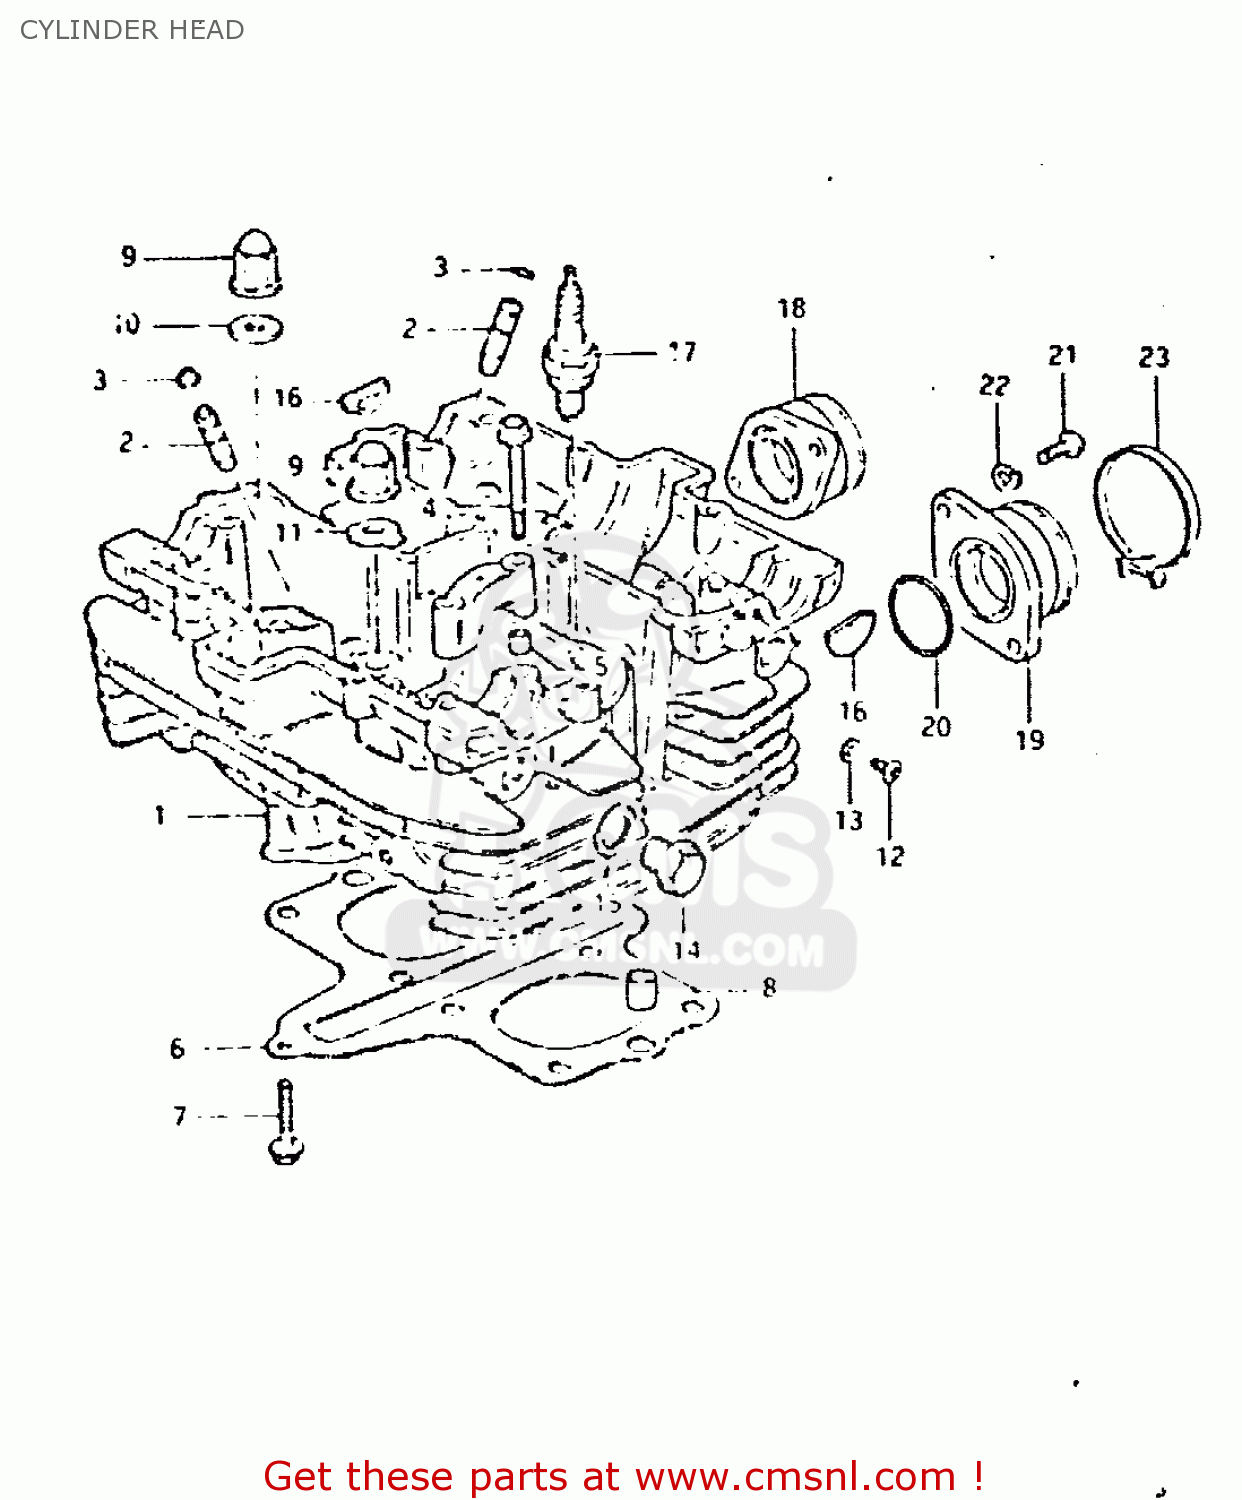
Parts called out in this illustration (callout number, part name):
1	CYLINDER HEAD SET
2	GUIDE,INTAKE VALVE
3	RING,SNAP
4	BOLT(6X39)
5	PIN(6.2X8X11)
6	GASKET (MCA)
7	BOLT
8	PIN
9	NUT
10	GASKET (NAS)
11	GASKET(10X22X2.3) (NAS)
12	SCREW
13	GASKET(5.3X9.3X1.2) (NAS)
14	PLUG (14X12)
15	GASKET(14X19.2X2) (NAS)
16	PLUG
17	SPARK PLUG DR8ES-L
18	PIPE,INTAKE,R
19	PIPE,INTAKE,L
20	O-RING
21	SCREW
22	LOCK WASHER
23	CLAMP
